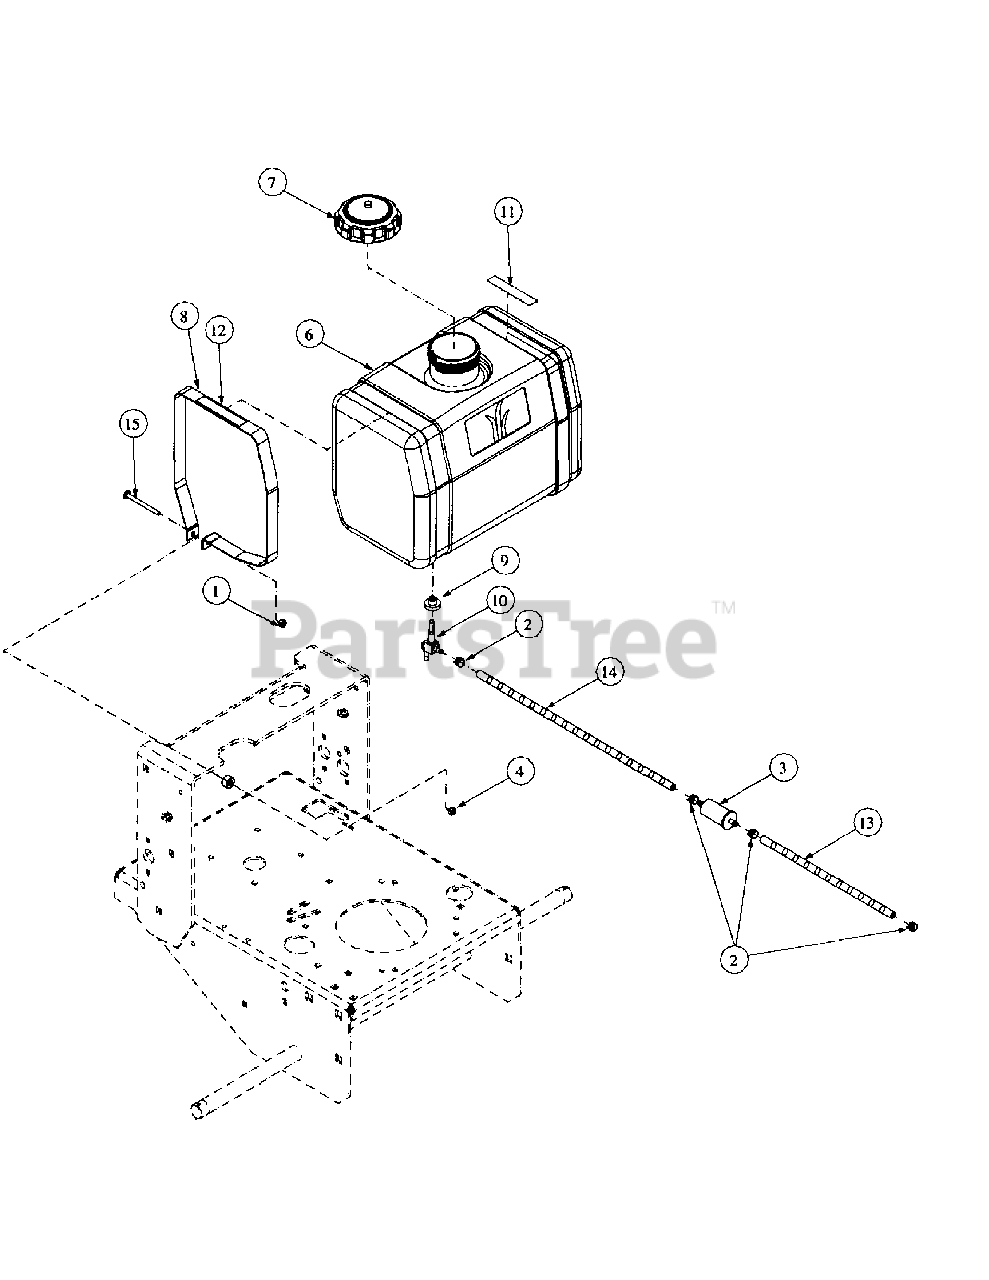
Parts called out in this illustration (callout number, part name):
1	Lock Nut, Nylon Insert, 1/4-20
2	Uni-Clamp
3	Fuel Filter
4	Nut, 1/4-20
5	Rubber Stop Pad
6	Fuel Tank
7	Fuel Cap, 3.5
8	Fuel Tank Strap
9	Grommet Fuel Tank
10	Shut Off Fuel Tank
11	Label, Mower Warning Turn Off Engine
12	Label, Mower Instruction, Fuel Valve
13	Hose Fuel, 12"
14	Hose Fuel, 18"
15	Carriage Bolt, 1/4-20 x 3.00
